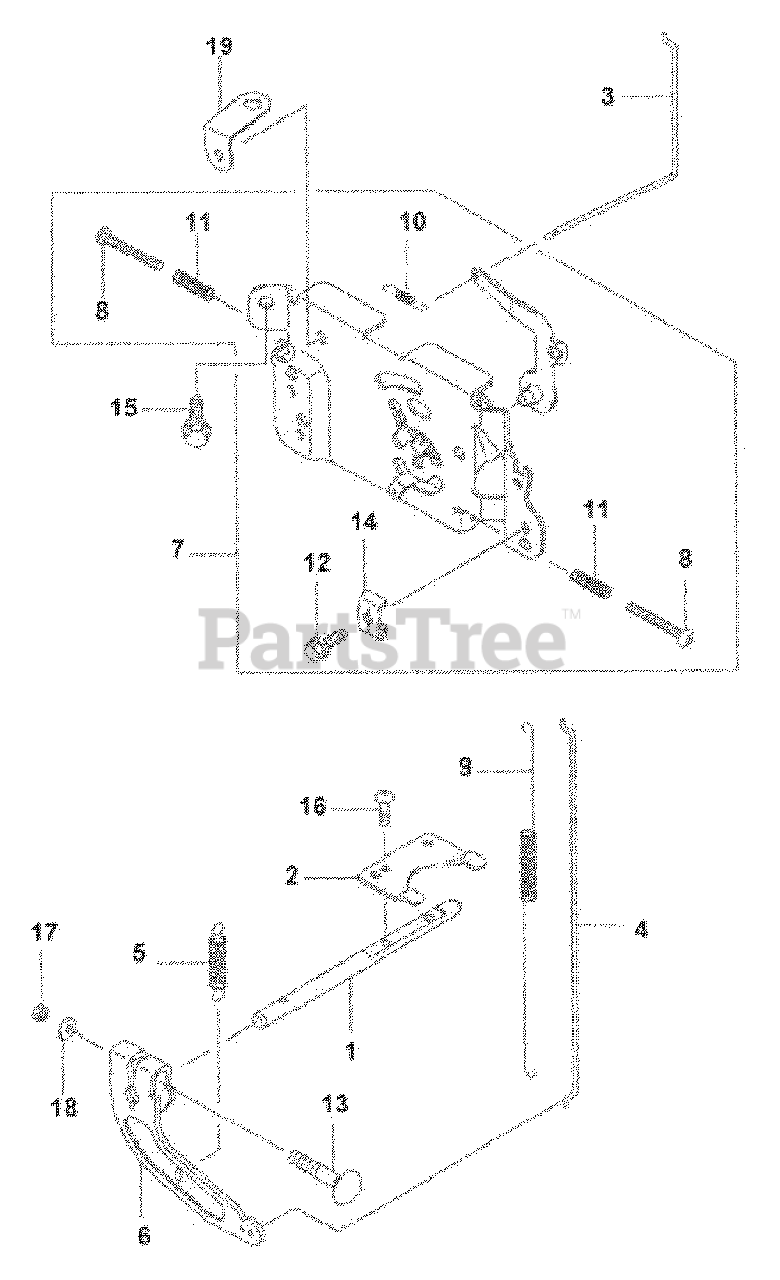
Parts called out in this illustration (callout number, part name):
2	Plate
5	Governor Spring
7	Control Panel
8	Screw, 4 x 35
10	Spring
13	Bolt, 6 x 35
15	Flange Bolt
16	Pan Screw
17	Hex Nut
18	Plain Washer
